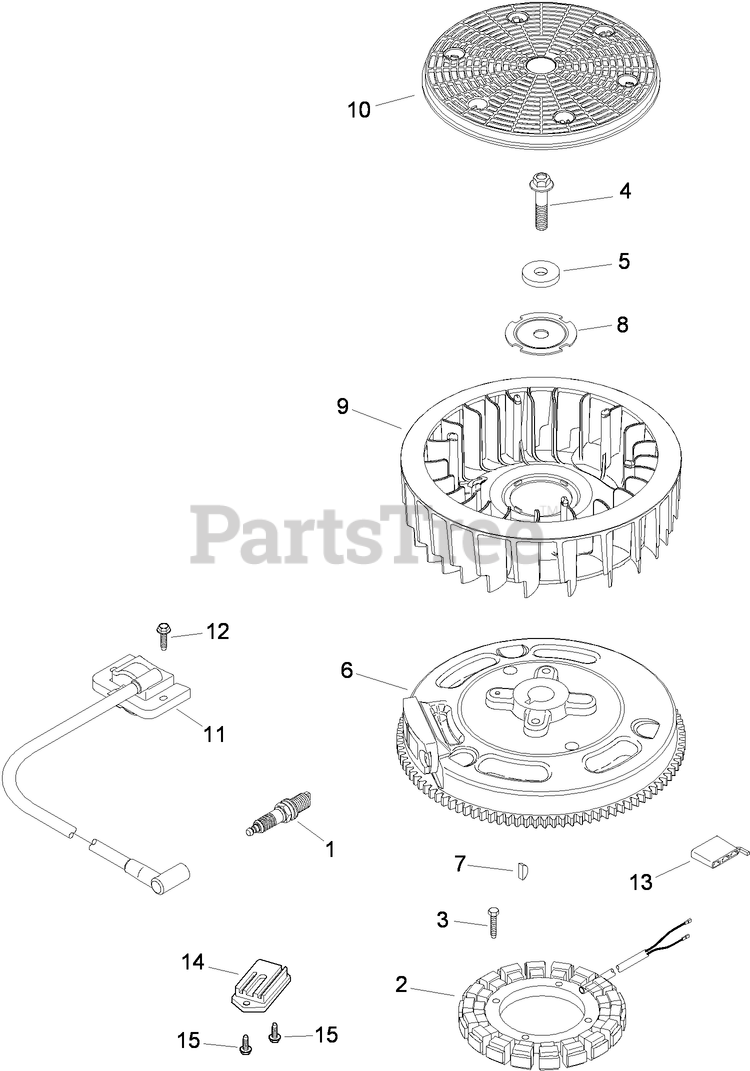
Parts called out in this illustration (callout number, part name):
1	SPARKPLUG
2	Kit, Stator (Incl. Terminal 25 452 01-S)
3	SCREW-THREAD FORMING (M5X0.8X25)
4	SCREW-FLANGE (M10X1.5X45)
5	WASHER-FLAT (13/32)
6	FLYWHEEL ASM
7	KEY (3/16 X 5/8)
8	PLATE-MOUNTING, FAN
9	Fan
10	SCREEN-GRASS
11	MODULE-IGNITION (C D I FIXED)
12	SCREW-FLANGE, THREAD FORMING (M5X.8X20)
13	CONNECTOR (3 CONTACT)
14	RECTIFIER/REGULATOR
15	SCREW-FLANGED, THREAD FORMING (M6X1.0X11)
